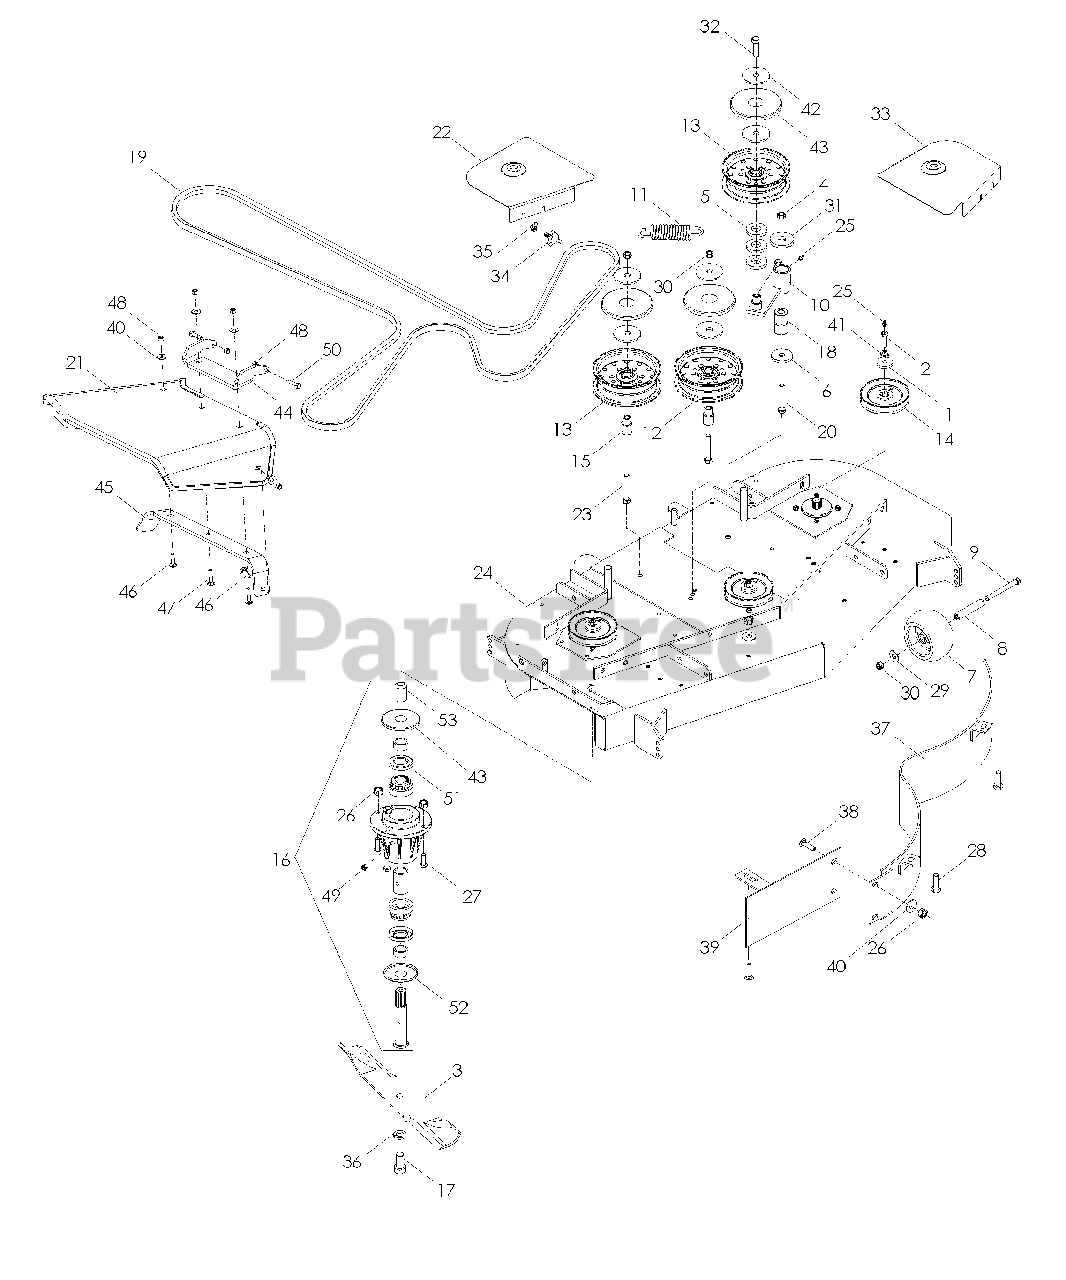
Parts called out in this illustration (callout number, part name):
1	WASHER, HEAVY
2	HCS 7/16-20 x 1 1/2 GR8 SPEC
3	BLADE, 18"
4	NUT 1/2-13 HEX NYLOC
5	BUSHING 5/8 MACHINERY
6	WASHER, SUPPORT
7	ROLLER, ANTI-SCALP
9	HCS 3/8-16 x 3 1/2 GR8
10	ARM, IDLER
12	PULLEY, IDLER
13	PULLEY, IDLER
15	BUSHING, IDLER
16	SPINDLE ASM
17	HCS 5/8-18 x 1 1/4
18	BUSHING, PIVOT
19	BELT, DECK
20	HCS 1/2-13 x 3 1/4
21	CHUTE, RUBBER
22	SHIELD, RT
23	HCS 3/8-16 x 3
24	DECK W/DECALS
25	ZERK
26	NUT 5/16-18 HEX CTRLK
27	HCS 5/16-18 x 1
28	HCS 5/16-18 x 3/4
29	WASHER 3/8 FLAT
30	NUT 3/8-16 HEX CNTRLK
31	WASHER 1/2 STD FLT
32	HCS 3/8-16 x 1 1/4
33	SHIELD LT
34	KNOB W/STUD
36	WASHER 5/8 SLW
37	MAIN WLDMT
38	RHSNB 5/16-18 x 5/8
39	CENTER WLDMT
40	WASHER 5/16 STD FLT
41	WASHER 7/16 SLW
42	WASHER 3/8 SPECIAL
43	DUST CAP, TOP
44	BRACKET, PIVOT
45	REINFORCEMENT, BRACKT
46	RHSNB 5/16-18 x 1 1/4
47	RHSNB 5/16-18 x 1 1/2
48	NUT 5/16-18 HEX NYLOC
49	GREASE POPPET
50	HCS 5/16-18 x 1 1/4
51	SEAL, SHAFT
52	DUST CAP, BOTTOM
53	CAP, VINYL
